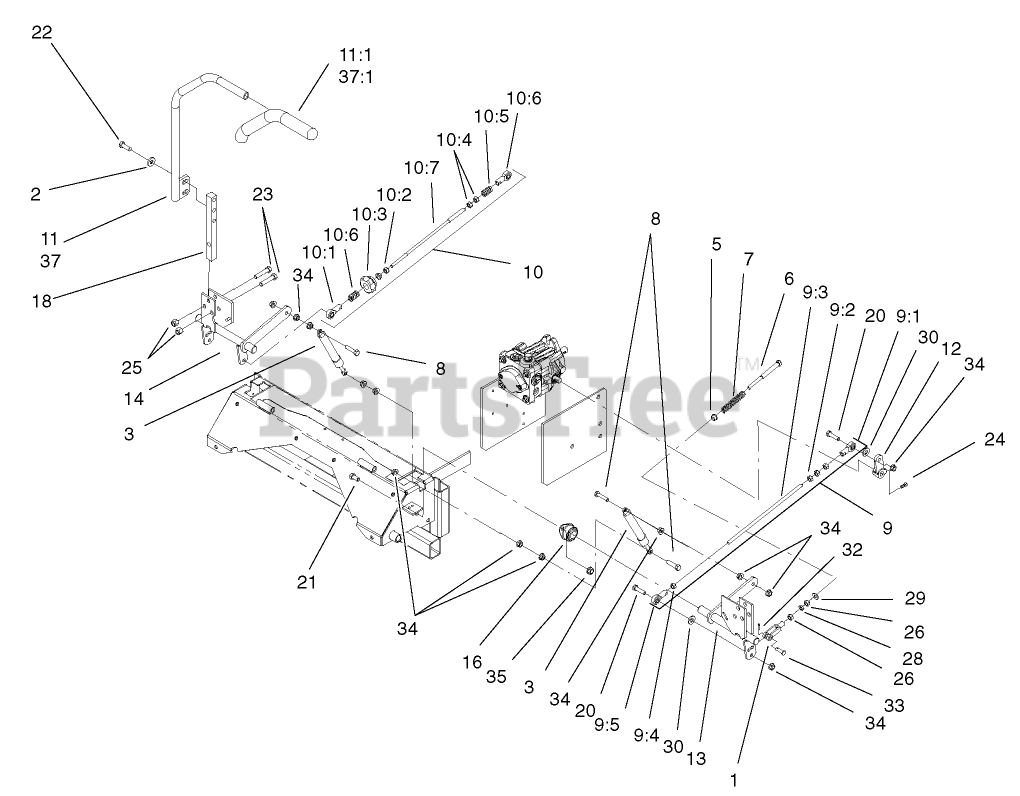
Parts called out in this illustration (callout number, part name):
1	YOKE-ADJUSTABLE
2	WASHER-BELLEVILLE
3	Damper-Control, Motion
5	BUSHING-FLANGED
6	BOLT-RETURN, NEUTRAL
7	SPRING-RETURN, NEUTRAL
8	SCREW-HH
9	LH Pump Linkage ASM
9:1	BALLJOINT-RH
9:2	NUT-HEX
9:3	LINKAGE-PUMP/LEVER
9:5	BALLJOINT-LH
10	Tracking Rod ASM
10:1	BALLJOINT-RH
10:2	NUT-HEX
10:3	KNOB-TRACKING
10:5	SPRING-COMPRESSION
10:6	BALLJOINT-LH
10:7	Link-Rod, Tracking
11	RH LEVER ASM
11:1	GRIP-CONTROL, MOTION
12	ARM-CONTROL, PUMP
13	CONTROL-MOTION, LH
14	CONTROL-MOTION, RH
16	BEARING-FLANGE, SIDE
18	ARM-SHAFT, CONTROL
20	SCREW-HH
21	SCREW-HH
22	SCREW-HH
23	SCREW-HH
24	SCREW-SET
25	NUT-LOCK, NI
26	NUT-HEX
28	NUT-JAM
29	WASHER-FLAT
30	WASHER-FLAT
32	PIN-COTTER
33	PIN-CLEVIS
34	NUT-HF
35	NUT-HHF, WHIZ
37	LH LEVER ASM
37:1	GRIP-CONTROL, MOTION
